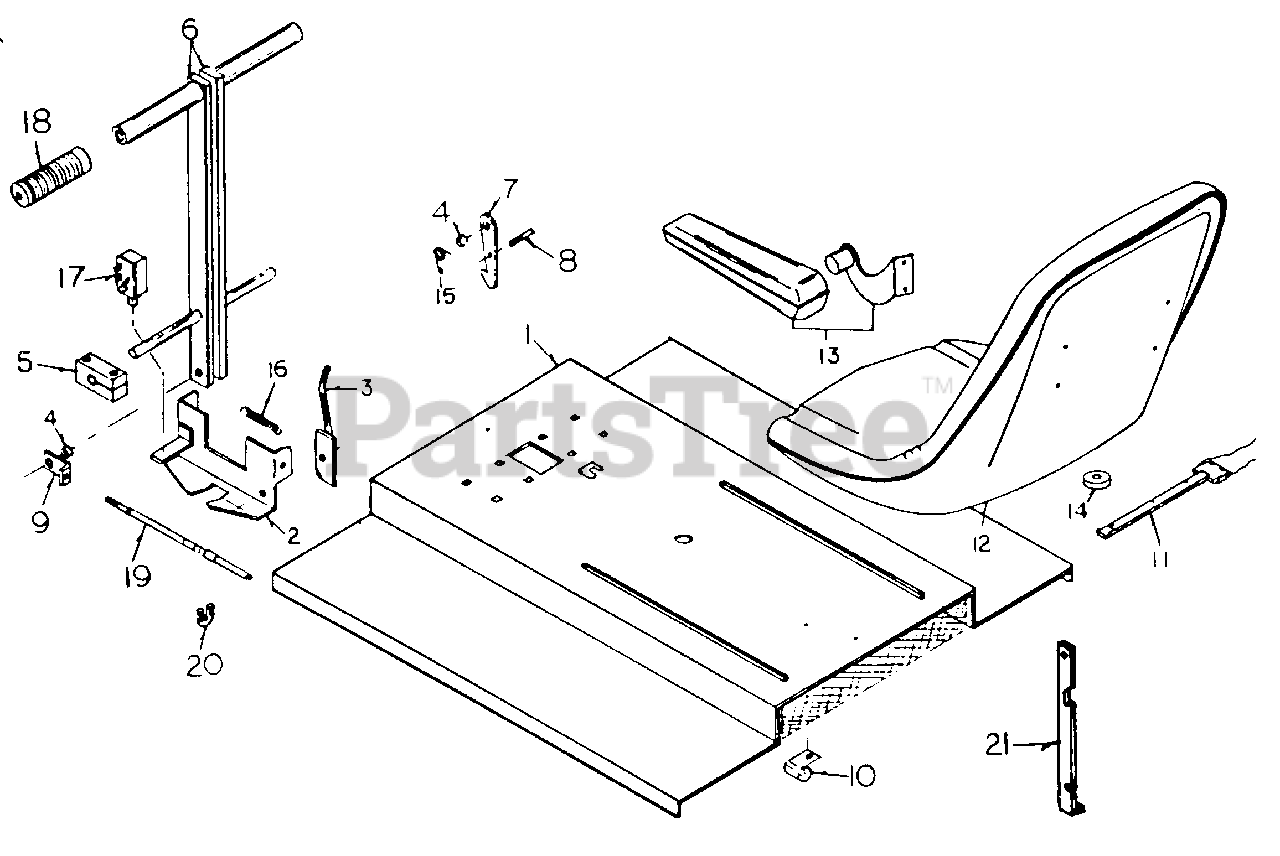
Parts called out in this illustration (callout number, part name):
3	Latch, Lever Lock
4	Bushing
6	Steering Lever
7	Seat Lid Latch
8	Seat Lid Latch Bolt
9	Steering Cable End
10	Seat Lid Harness Retainer
13	Arm Rest Kit
15	Seat Lid Latch Spring
16	Lever Lock Spring
18	Handle Grip
19	Steering Cable
20	Steering Cable Clamp
